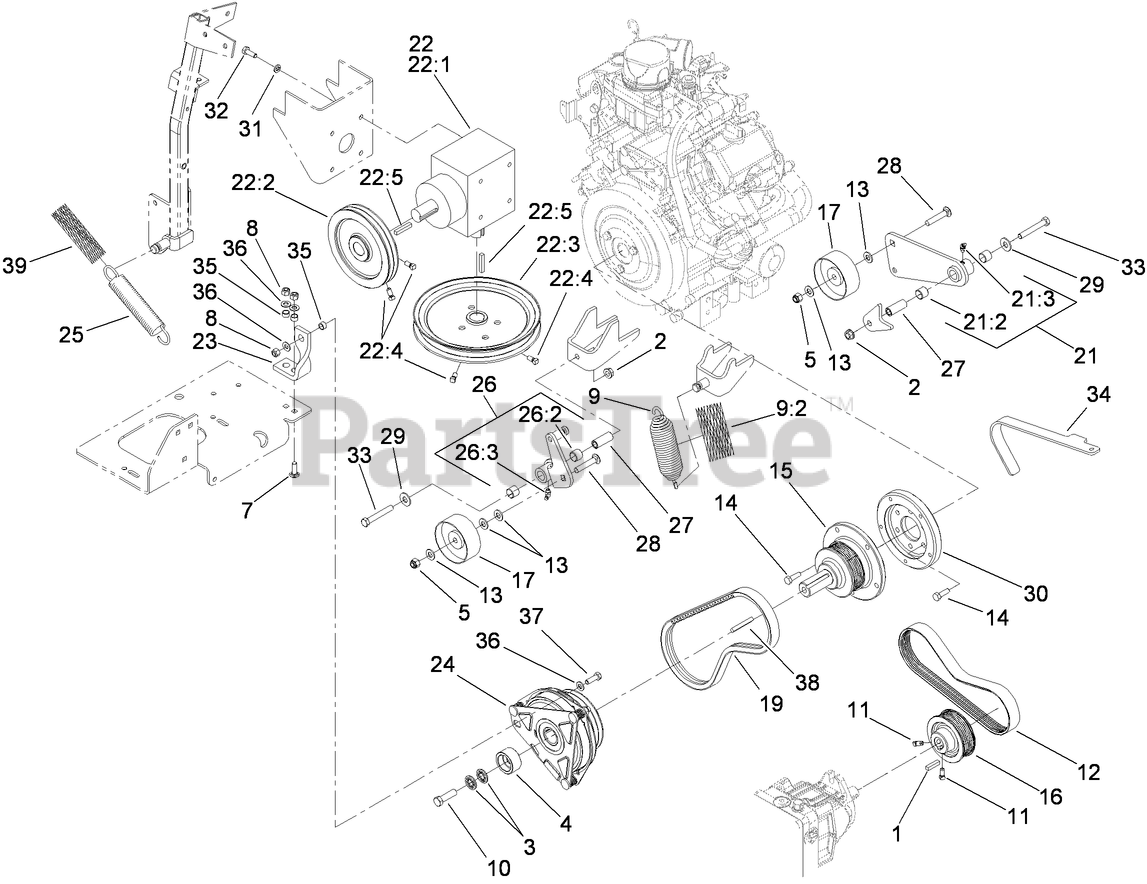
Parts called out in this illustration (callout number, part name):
2	NUT-HHF, WHIZ
3	WASHER-SPRING
4	RETAINER-CLUTCH
5	NUT-LOCK, NI
7	SCREW-CARR
8	NUT-LOCK, NI
9	DFI HYDRO SPRING KIT
9:2	COVER-SPRING
10	SCREW-HH
11	SCREW-SET
12	BELT-V
13	WASHER-FLAT
14	SCREW-HH
15	SHAFT-STUB
16	PULLEY
17	PULLEY-FLAT
19	BELT-V
21	IDLER ARM ASM
21:2	SLEEVE-BEARING
21:3	FITTING-GREASE
22	GEARBOX
22:1	GEARBOX-90 DEG
22:2	PULLEY
22:3	PULLEY
22:4	SCREW-SET
22:5	KEY-SQUARE
23	STRAP-STOP, CLUTCH
24	CLUTCH-ELECTRIC
25	SPRING-IDLER, DECK
26	IDLER ARM ASM
26:2	SLEEVE-BEARING
26:3	FITTING-GREASE
27	BUSHING
28	SCREW-CARR
29	WASHER-FLAT
30	ADAPTER-SHAFT, STUB
31	WASHER-LOCK
32	SCREW-HH
33	SCREW-HH
34	TOOL-ALIGNMENT, PULLEY
35	SPACER
36	WASHER-PLAIN
37	SCREW-HH
38	KEY-SQUARE
39	COVER-SPRING
